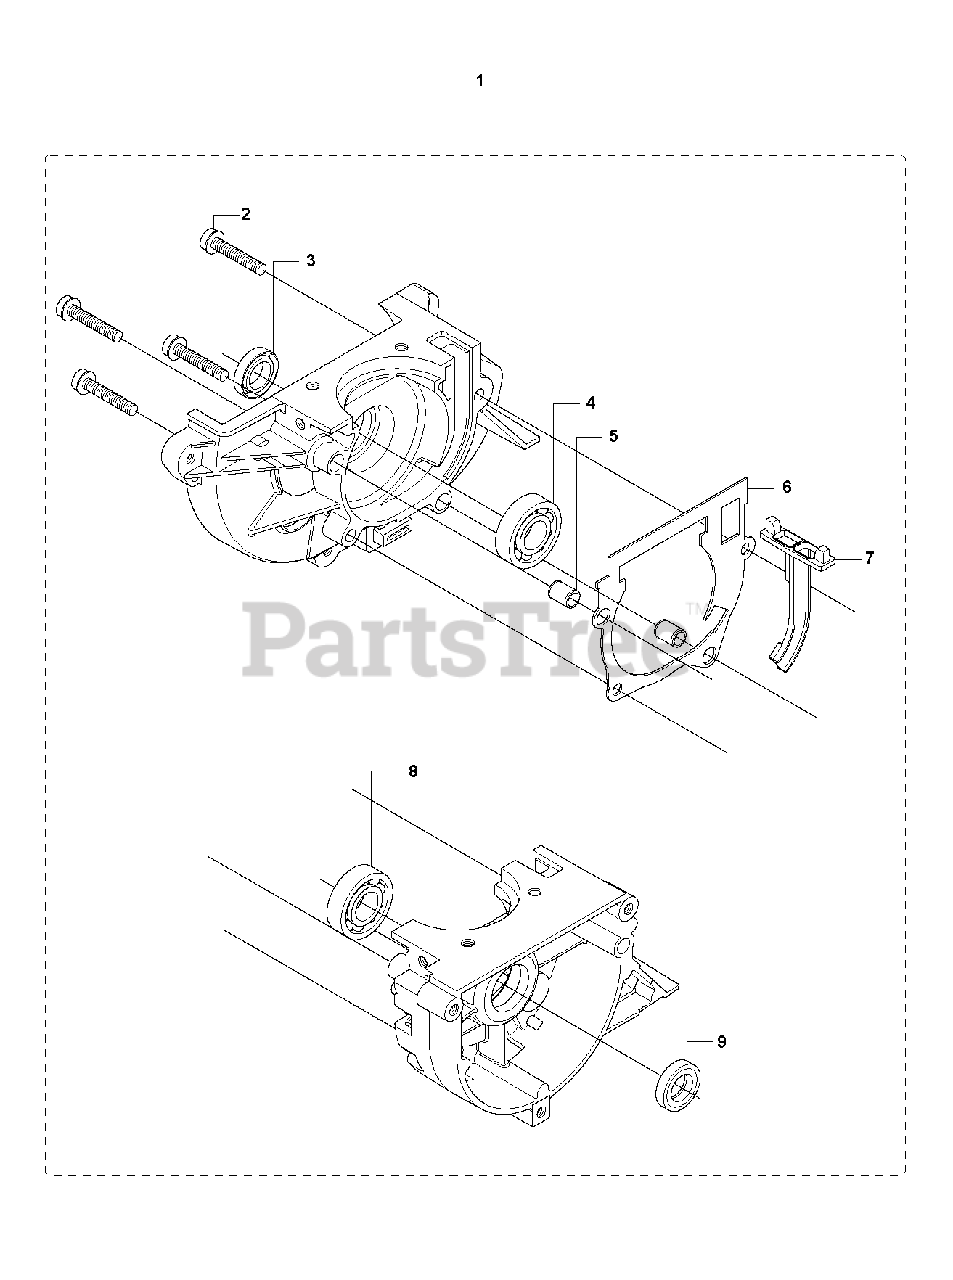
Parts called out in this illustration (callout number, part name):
1	CRANKCASE CPL
2	SCREW
3	SEALING RING
4	BALL BEARING
5	SLEEVE
6	GASKET
7	INSERT, CARTER
8	BALL BEARING
9	SEALING RING
